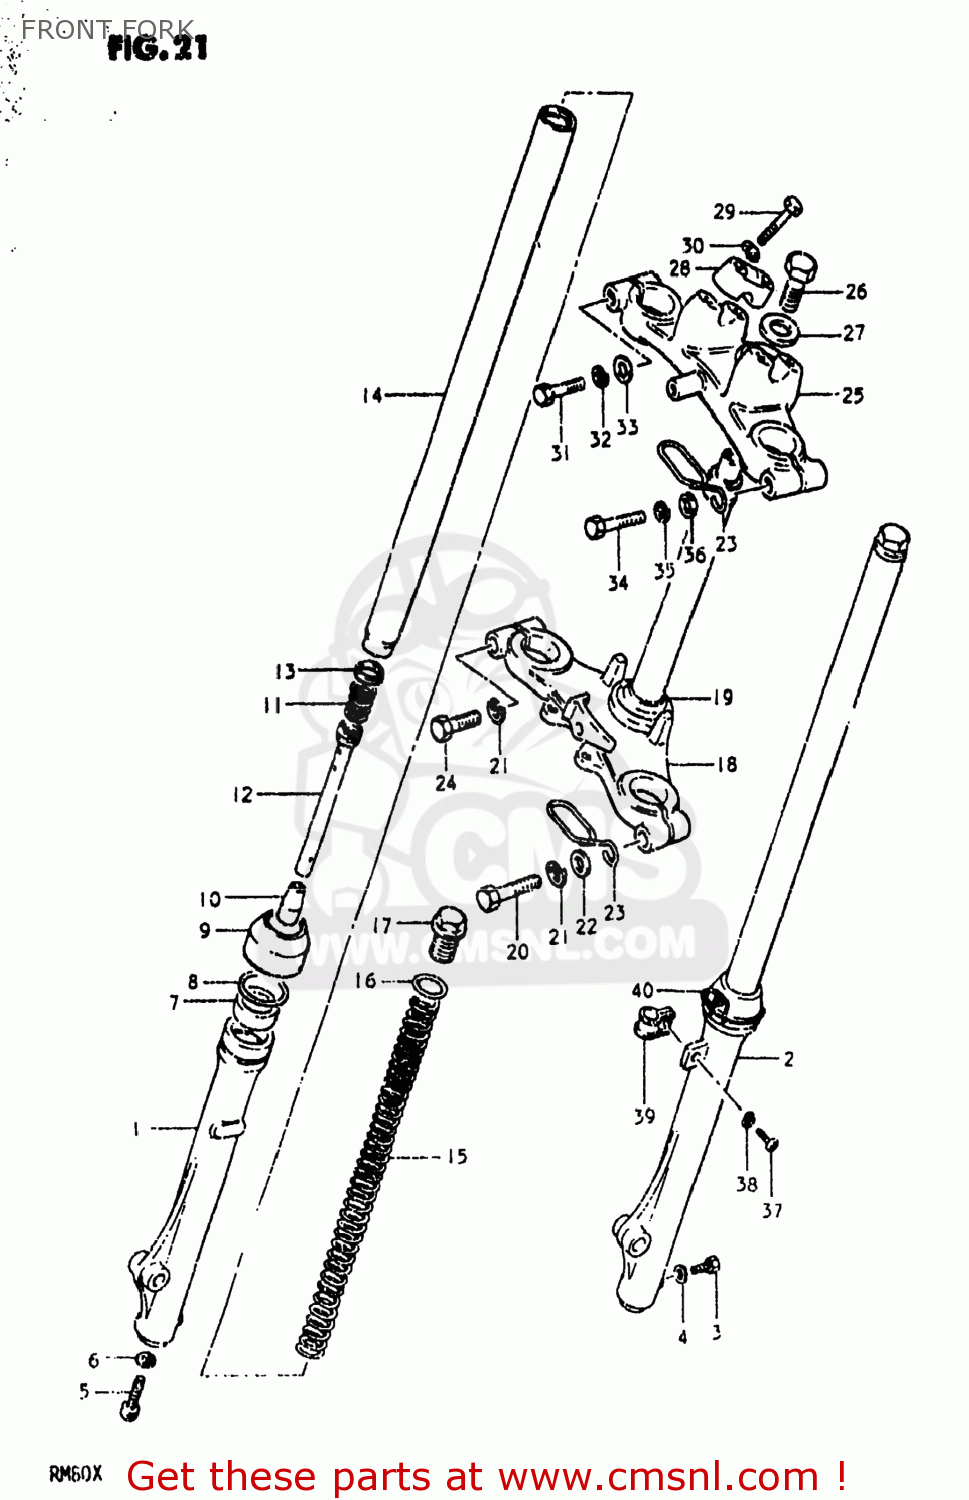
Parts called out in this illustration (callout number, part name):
0	DAMPER SET
1	TUBE,OUTER
2	TUBE,OUTER,LEFT
3	BOLT(6X8)
4	GASKET,DRAIN,PLUG (NAS)
5	BOLT(8X27)
6	GASKET (NAS)
7	OIL SEAL,FRONT FORK
8	CIRCLIP,FORK OIL SEAL
9	DUST SEAL,FRONT FORK
10	PIECE,OIL LOCK
11	SPRING,REBOUND
12	CYLINDER,FRONT FORK
13	RING,PISTON
14	TUBE,FORK,INNER
15	SPRING,FRONT FORK
16	O RING
17	BOLT
18	STEM,STEERING
19	RACE,STEERING OUTER LWR
20	BOLT
21	LOCK WASHER
22	WASHER
23	GUIDE,CABLE
24	BOLT,M10X1.25X
25	HEAD,STEERING STEM
26	BOLT,STEERING STEM HEAD
27	WASHER
28	HOLDER,HANDLEBAR
29	BOLT
30	LOCK WASHER
31	BOLT 8X40
32	LOCK WASHER
33	WASHER
34	BOLT 8X45
35	LOCK WASHER
36	WASHER
37	SCREW
38	LOCK WASHER
39	CLIP,FR BRAKE CABLE
40	GUIDE,CABLE
